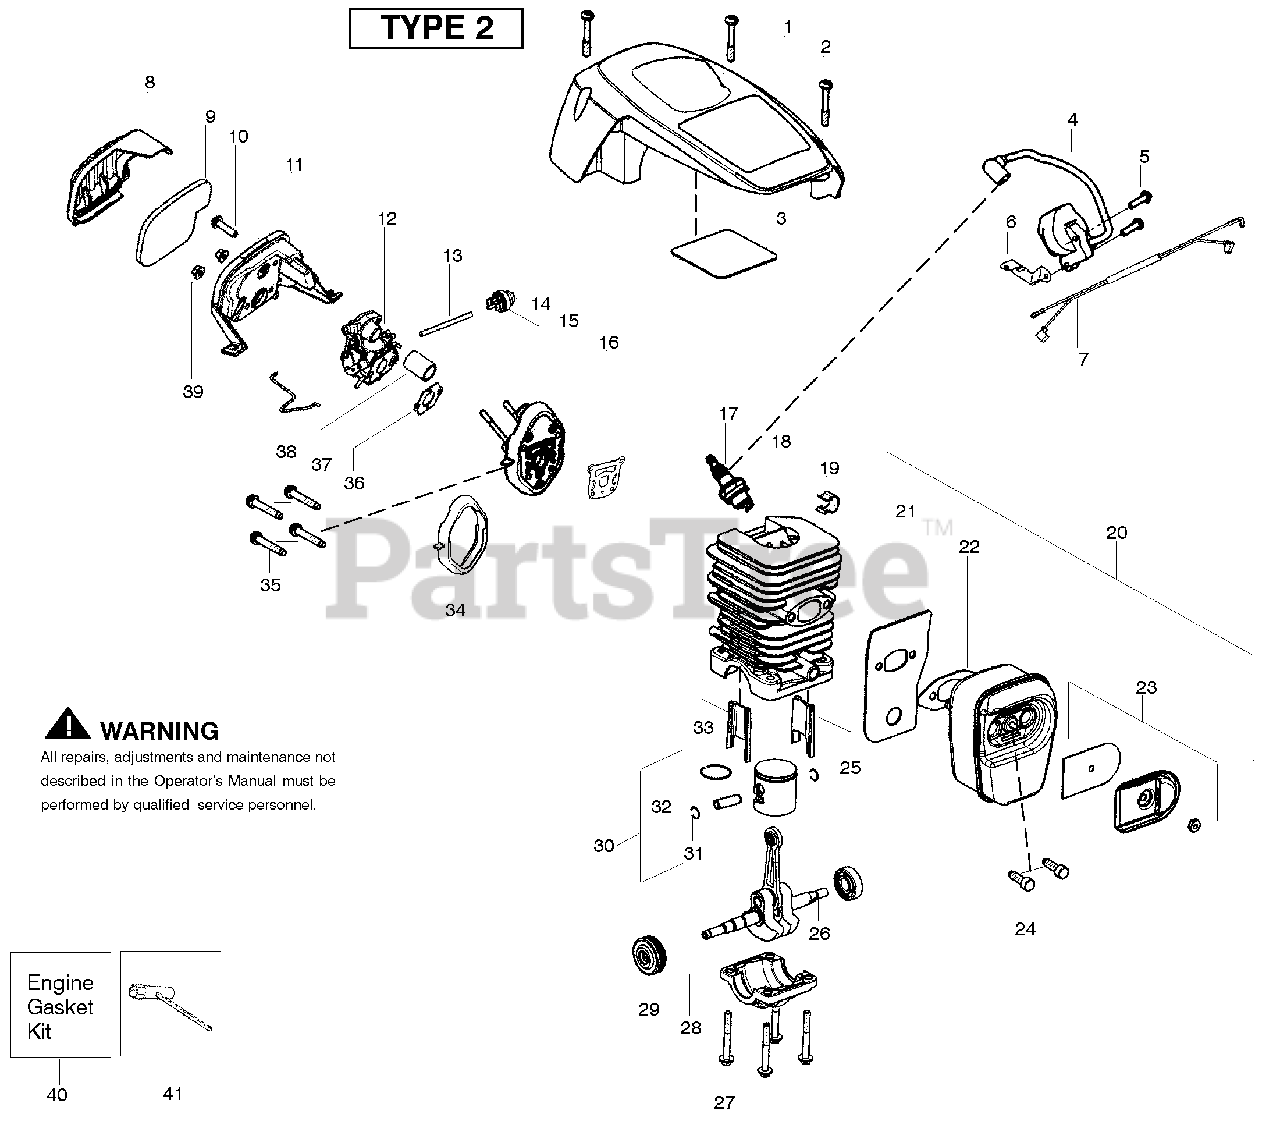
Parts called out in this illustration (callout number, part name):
1	Shield-Cylinder
3	Reflector-Tape
4	Module - Ignition
6	Strap-Ground
7	Assy-Wire Harness
8	Cover-Air Filter
9	Filter-Air
11	Housing-Air Filter
12	Carburetor Zama W-26
13	Kit-Fuel Line (Small)
14	Bulb-Purge "snap-in"
15	Kit-Carb. Adaptor
16	Gasket-cyl. o-ring (kit)
17	Accy-Spark Plug (RCJ-7Y)
18	Kit-Cylinder
19	Clip-High Tension Lead
20	Kit-Muffler
21	Backplate-Muffler
22	Gasket-Muffler (kit)
23	Kit-Spark Arrestor
24	Bolt-Muffler
25	Insert-Left (black) Cyl.
26	Assy-Crankshaft/Rod
28	Cap-Crankcase
29	Assy-Bearing/Seal
30	Kit-Piston
31	Retainer-Piston Pin
32	Ring-Piston
33	Insert-Right (gray) Cyl.
34	Seal-Adaptor (kit)
36	Gasket-Carb. (kit)
37	Tube-Intake
38	Wire-Throttle
39	Nut-Carb.
40	Kit-Gasket
41	Wrench-Bar
